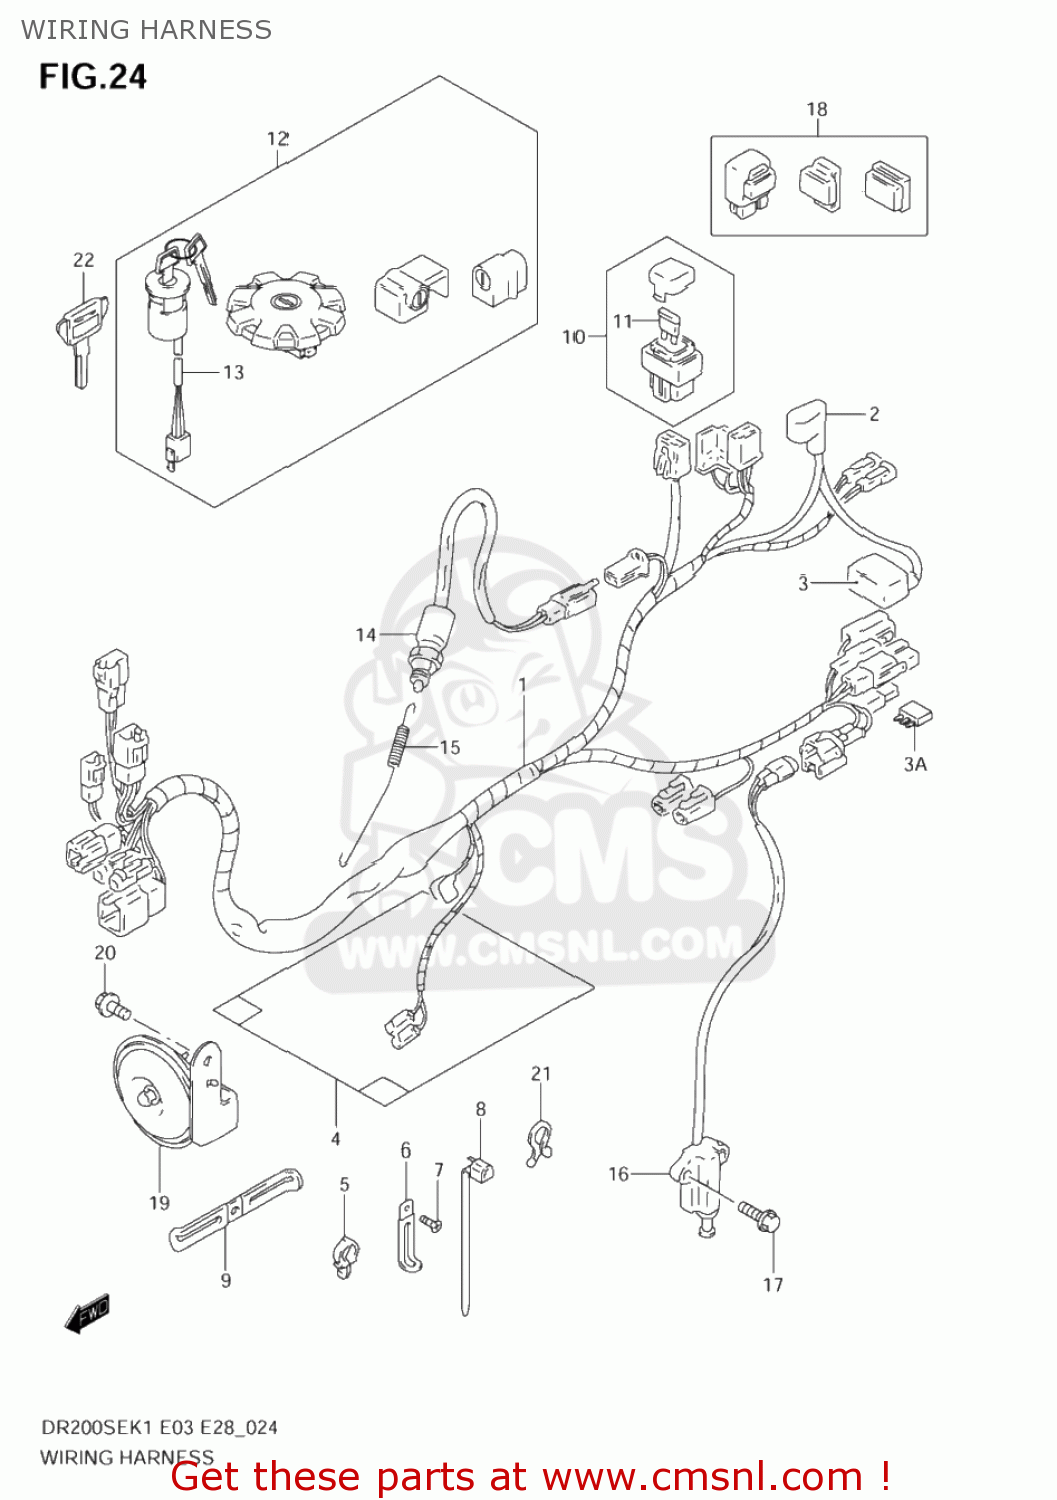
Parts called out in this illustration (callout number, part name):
1	HARNESS,WIRING
2	CAP,STARTER RELAY
3	CAP,BATTERY PLUS
3A	DIODE(STANLEY DE8804)
4	COVER,WIRING HARNESS
5	CLAMP
6	CLAMP(L:45)
7	SCREW
8	CLAMP(L:95)
9	CLAMP,STARTER MOTOR LEAD
10	BOX ASSY,FUSE
11	FUSE(20A)
12	LOCK SET
13	SWITCH ASSEMBLY,IGNITION
14	SWITCH ASSY,STOP LAMP
15	SPRING
16	SWITCH ASSY,SIDE STAND
17	BOLT
18	RELAY ASSY
19	HORN ASSY
20	BOLT
21	CLIP(ID:11.5)
22	KEY,BLANK(TYPE:C)
